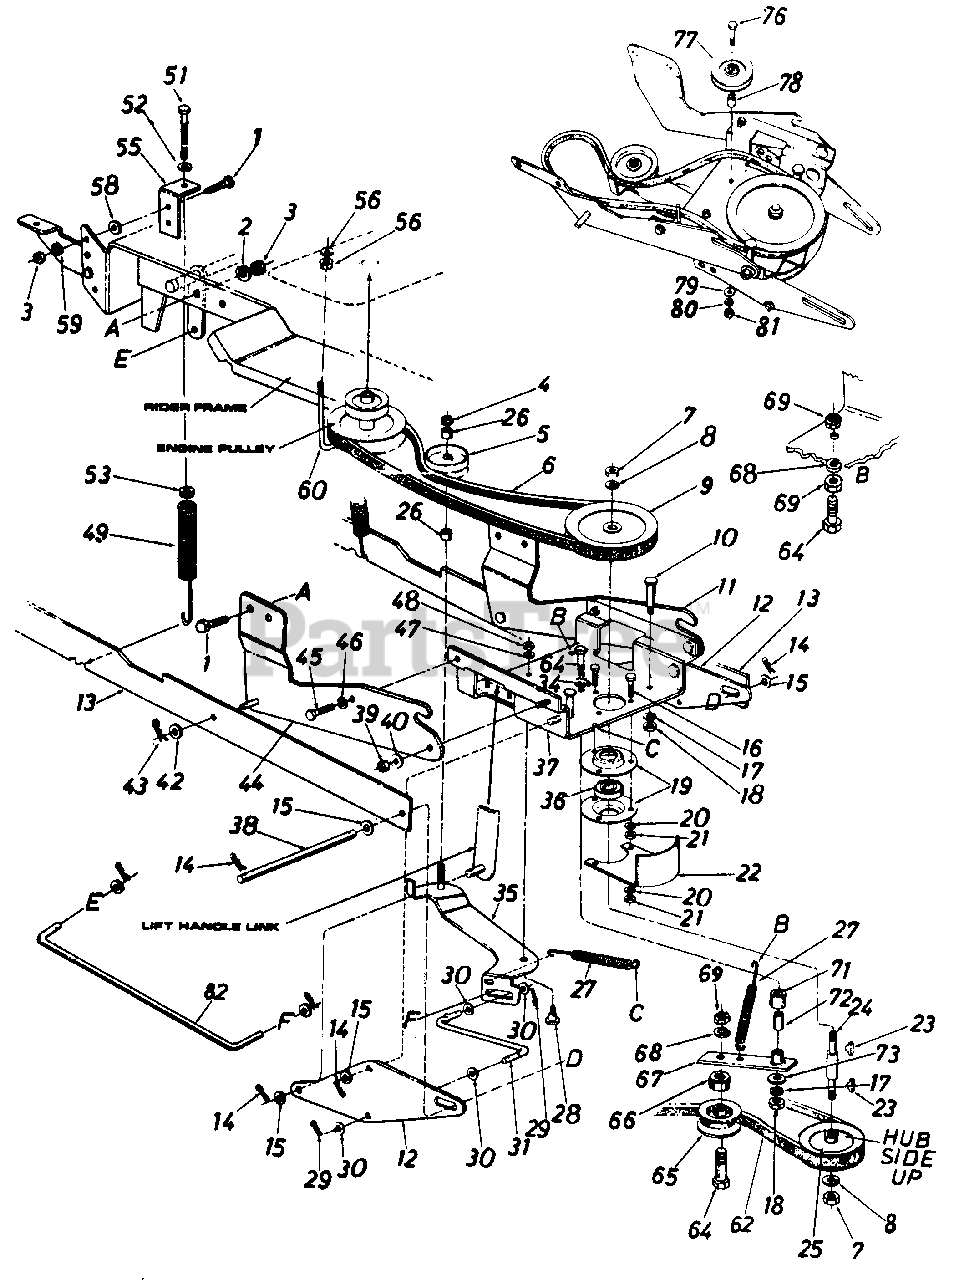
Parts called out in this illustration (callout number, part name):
1	Hex Bolt 1/4-28 x .75" Lg. Grade 5
2	L.-Wash. 1/4" I.D.*
3	Hex Nut 1/4-28 Thd.*
4	Hex Cent. L-Nut 3/8-16 Thd .
5	Idler Pulley
6	"V"-Belt 1/2 x 49" Lg.
7	Hex Jam Nut 5/8-11 Thd
8	L-Wash 5/8" I.D.*
9	6.50" O.D. x 5/8 Pulley
10	Shoulder Bolt
11	Channel Supporting Brkt.- R.H.
12	Linkage Brkt.
13	Linkage Arm Ass'y.
14	Intern. Cotter Pin .50 Dia.*
15	Fl.-Wash.
16	Hex Bolt 5/16 x 1.25" Lg.
17	L.-Wash. 3/8" I.D.*
18	Hex Jam Nut 3/8-16 Thd.
19	Bearing Housing
20	L.-Wash. 5/16" I.D.*
21	Hex Nut 5/16-18 Thd.*
24	Pulley Spindle
25	5/8 Pulley-6.28 I.D. x 5.56 O.D.
26	Spacer .383 I.D. x .503 O.D. x .562 Lg.
27	Extension Spring .54 O.D. x 5.25"
28	Shoulder Bolt
29	Cotter Pin 3/32" Dia. x 1.0"*
30	F l.-Wash.
31	Control Rod
34	Hex Sems Scr. 5/16-18 x 1.0" Lg.*
35	Clutch Idler Brkt. Ass'y.
36	Ball Bearing
37	Channel Ass'y.
38	Lift Handle Shaft
39	Hex Jam Nut 3/8-16 Thd.
40	L.-Wash. 3/8" I.D.
42	FI .-Wash.
43	Intern. Cotter Pin .50" Dia.*
44	Channel Supporting Brkt.- L.H.
45	Hex Bolt 3/8-16 x x 1.0" Lg.*
46	L.-Wash. 3/8" I.D.*
47	L.-Wash. 5/16" I.D.*
48	Hex Nut 5/16-18 Thd.*
49	Helper Spring
51	Hex Scr. 5/16-18 x 2.0" Lg. Special
52	Bell Wash. .345 I.D. x .88 O.D. x .06
53	Spring Insert
58	Fl.-Wash. .264" I.D.
59	L.-Wash. 1/4" I.D.*
60	J-Bolt 5/16-18 Thd .
62	"V"-Belt 1/2 "A" x .89" Lg.
64	Hex Bolt 3/8-16 x 2.0" Lg.*
65	Idler Pulley
66	Spacer .385 I.D. x .503 O.D. x.562" Lg.
67	Idler Arm Ass'y.
68	L.-Wash. 3/8" I.D.*
69	Hex Jam Nut 3/8-16 Thd.
71	Spacer .380" I.D. x 1.0" I.D.
72	Spacer .3775 I.D. x .600.D. x8.3 Lg.
73	Fl.-Wash. 3/8 I.D. x 1" O.D x 1.27
76	Hex Bolt 3/8-16 x 2.5" Lg. (Grade 5)
77	Idler Pulley .38 I.D. x 3.06 O.D.
78	Spacer .385 I.D. x .630 O.D. x .76 Lg. I
79	Fl.-Wash. .39 I.D. x 1-3/4 O.D. x 3/1 6"
80	L-Wash. 3/8" I.D.*
81	Hex Nut 3/8-16 Thd.*
82	Clutch Control Rod 13.67" Lg.
